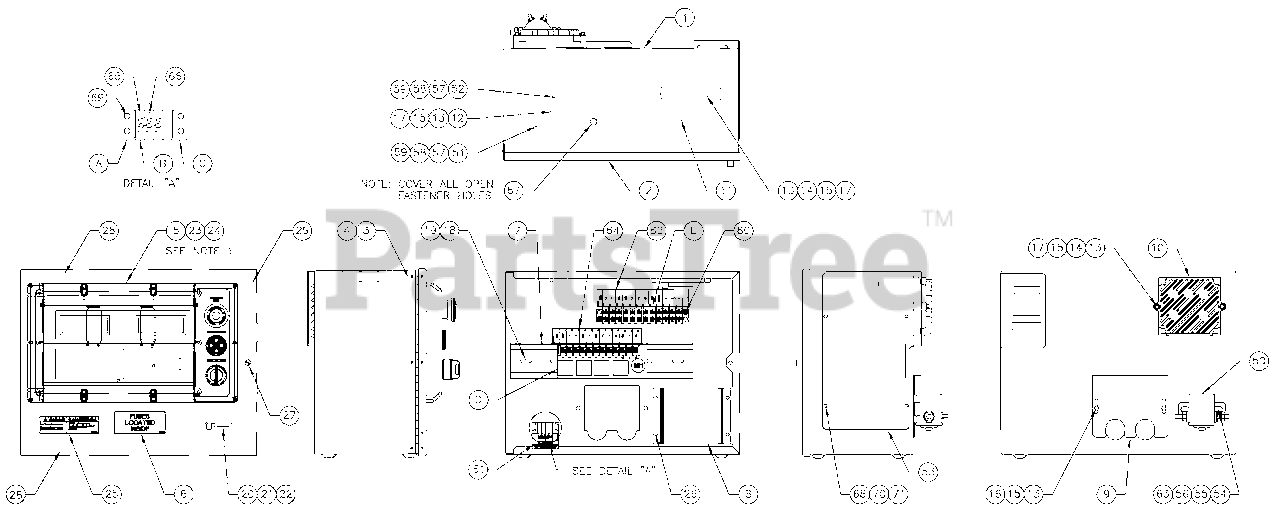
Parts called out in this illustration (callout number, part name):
1	ENCLH/G CONTROL PANEL
2	COVER CONTROL PANEL
3	HINGE CONTINUOUS H PANEL
4	RIVET POP .125X .275SS
5	ASSYPROGRAMMEDH-100
6	DECAL FUSES LOCATED INSIDE
7	RAILSNAPTRACK PCB HOLDER BULK (12" LG)
8	ASSYPCB 2AMP 12V ULBATTCHGR
9	PLATE HARNESS CLAMP
10	ASSYPCB PWRAVRW/AMP HEADER
11	ASSYPCB BOSCH GOV DRIVER
12	DIO BRIDGE25A 600V
13	WASHER LOCK M5
14	SCREW PPHM M5-0.8X 30SS
15	WASHER FLAT M5
16	SCREW HHPM M5 0.8X12
17	NUT HEXM5 0.8G8 YELCHR
18	WASHER FLAT M4
19	SCREW PHTT M40.7X 10ZYC
20	CONN DUST CAP W/CHAIN DB9
21	WASHER FLAT M3.5
22	SCREW PHTT M3.5 0.6X 10
23	SCREW PPHM M4-0.7X 8 BLXOX
24	WASHER LOCK #8 M4
25	DECAL WRNB ATT CHRG12/24VBI
26	SCREW PHTT M40.7X 12ZYC
27	M5 0.8 CAPTIVE PANEL KNLDHD
28	SEAL COVER 3.18 X 12.7X 382
29	SEAL COVER 3.18 X 12.7X 283
50	RELAY CONTACTOR 12VDC
53	COVER CONTROL PANEL SIDE
54	SCREW HHC 1/4-20X3/4G5
55	WASHER FLAT M6-1/4
56	WASHER LOCK M6-1/4
57	WASHER LOCK M3
58	NUT HEXM3 0.5G8 YELCHR
59	WASHER FLAT M3
60	SCREW PHTT#6-32X5/8ZYC
61	DECAL CPL CONTROL PANEL FUSES
62	DECAL CPL 5.4/6.8LTB3
63	NUT HEX 1/4-20 STEEL
64	DECAL CPL 5.4/6.8L RELAY BOARD
65	FUSE ATO TYPE 15 AMP (BLUE)
66	FUSE ATO TYPE 10 AMP (RED)
67	SEAL WEATHER.45"DIA
68	SCREW PPHM M5-0.8X 12ZNC
69	SCREW PHTT#6-32X3/8ZYC
70	WASHER FLAT M5
71	WASHER LOCK M5
A	ADPTR RH SIDE WICKMANN 178.6191
B	HOLDERFUSE WICKMANN 178.6150
C	ADPTR LH SIDE WICKMANN 178.6192
D	ASSYPCB G PANEL RELAY 12VDC
E	BLOCK TERM 20A 12X 6 X1100V
